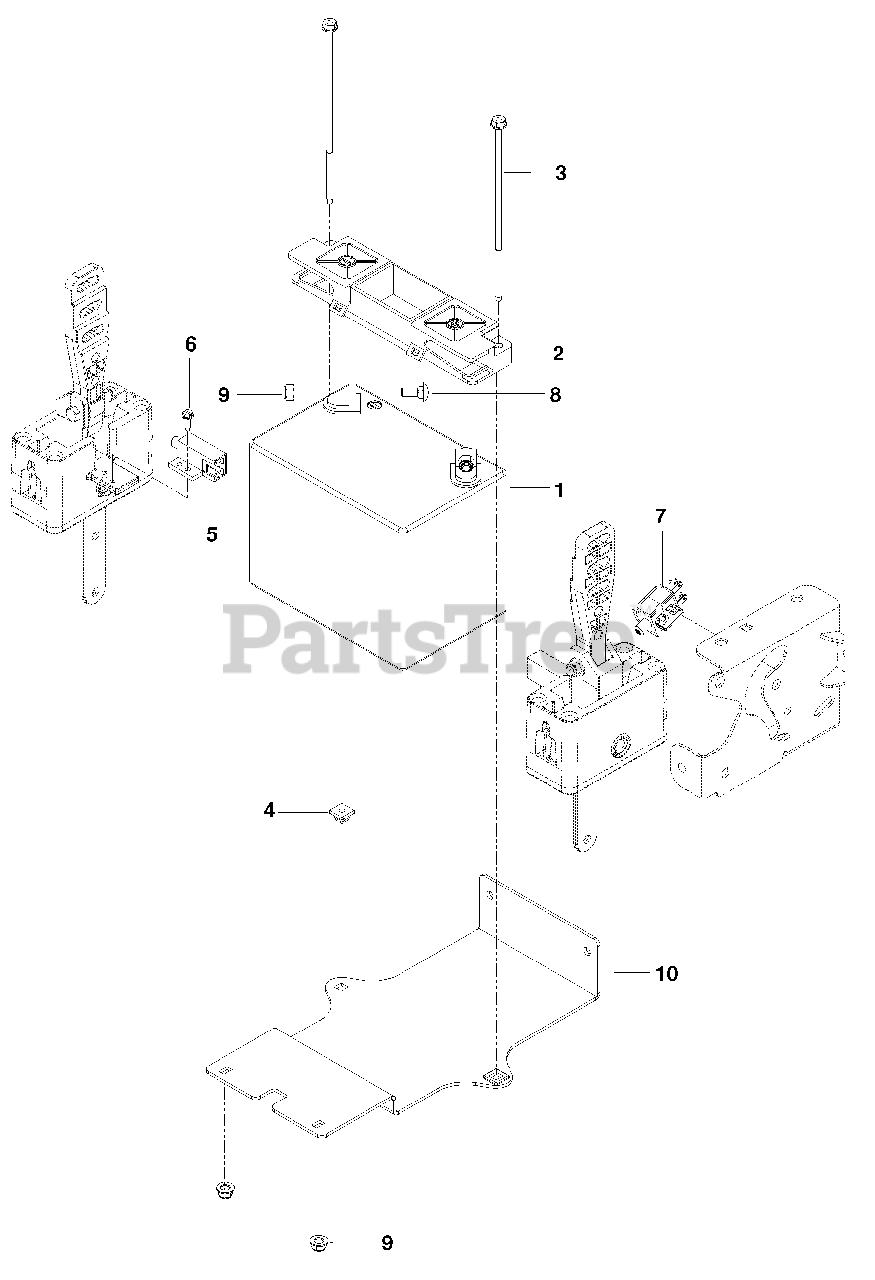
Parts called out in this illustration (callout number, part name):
1	BATTERY
2	BATTERY HOLD DOWN
3	BOLT, 1/4 x 7 1/2
4	NUT 1/4 PUSH, NYLON
5	SWITCH, INTERLOCK
6	SCREW #10-24 x 5/8 WSH HD
7	SWITCH, BRAKE
8	BOLT, 5/16-18 x 3/4
9	NUT 5/16-18 FLANGE NYLOC
10	PLATE, BATTERY
